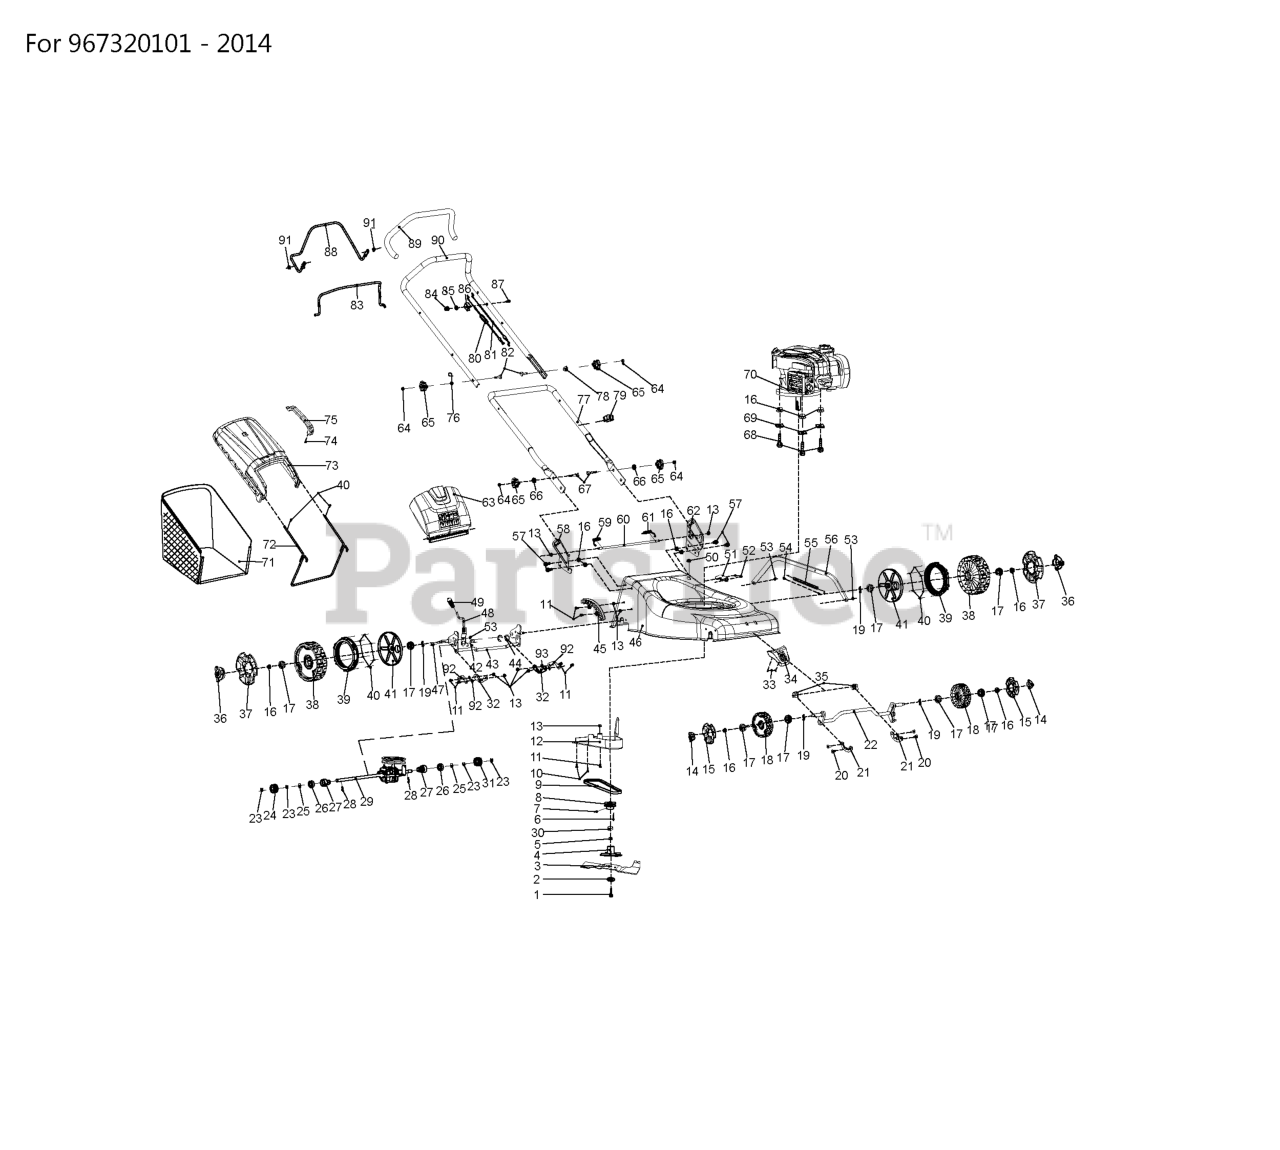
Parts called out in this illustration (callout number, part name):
11	SCREW M6*16 #26800204601
13	LOCK NUT M6,GB/T6187.1-2000 #2
14	WHEEL COVER 6" #25340700101
16	LOCKING BOLT M8,GB6187.1 #2680
19	WASHER Ï?12 #26800706202
23	WASHER Ï?9,GB896 #26800900201
25	WASHER Ï?12.8*Ï?20*0.8 #268007
27	BEARING HOUSING #26900211501
32	FIXING PLATE #26300124401
36	WHEEL COVER 8" #25341000101
37	WHEEL COVER 8" #25341100101
38	WHEEL 8" #25341200101
39	GEAR WHEEL #25229900201
41	COVER #25342800101
42	WASHER Ï?19*1.5,GB896 #2680090
44	WASHER #26300107601
45	SEGMENT #25214200102
47	WASHER M6*14 #26800203001
49	KNOB HEIGHT ADJUSTMENT #25341
50	COVER #25217800104
52	BOLT M6*12,(GB5787-86)GB6674.1
53	LOCKING BOLT M6,GB889.1 #26800
54	TUBING #29000300101
55	SPRING #26801103903
57	BOLT M8*16 #26800606401
59	SPRING #26801125501
61	BRACKET #26801125401
64	HEXAGON NUT #26800502301
65	KNOB #25341500101
71	GRASSBAG #25100173001
72	BRACKET #26300299201
73	COVER GRASS CATCHER #253417001
74	SCREW ST4.8*19,GB845 #26800104
75	HANDLE #25341800101
93	O-RING #25100175201
